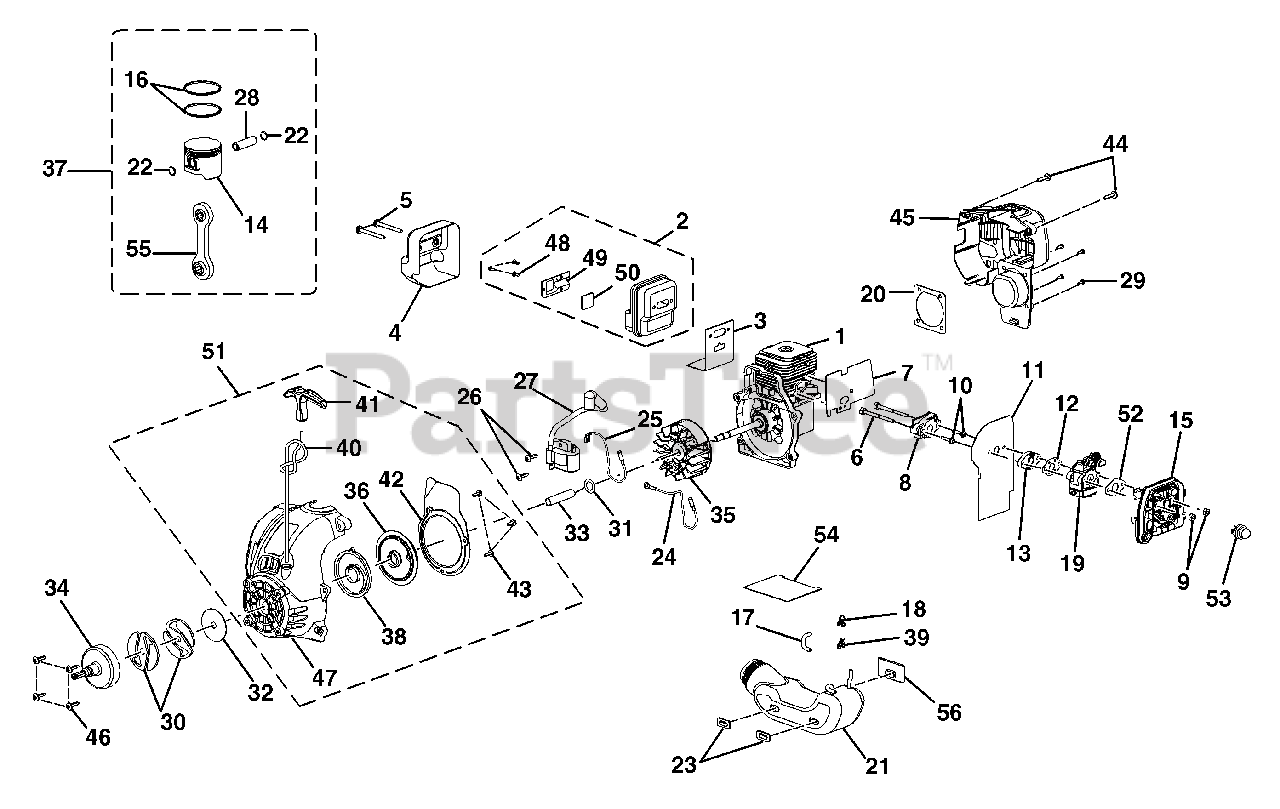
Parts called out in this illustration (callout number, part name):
1	SHORT BLOCK ASSEMBLY
2	MUFFLER ASSEMBLY
3	MUFFLER GASKET
4	HEAT SHIELD
5	SCREW (10-24 X 2-1/8 in. TORX TRUSS HD. SEMS)
6	BOLT (10-27 X 2-3/8 in HEX HD.)
7	HEAT DAM GASKET
9	LOCK NUT (10-24)
10	SCREW (10-24 X 1 in. TORX PAN HD.SEMS)
11	CARBURETOR GASKET
12	CARBURETOR GASKET
14	PISTON W/PIN
15	AIR FILTER BOX
16	PISTON RING 30cc
17	RUBBER TUBING (2 in)
19	CARBURETOR
20	GASKET, C/C COVER
21	FUEL TANK ASSEMBLY
22	RETAINING RING
24	LEAD W/TERMINALS
26	SCREW (8-32 X 1 in. THREAD FORMING)
27	IGNITION MODULE (W/ 3 SEC. KILL)
28	PISTON PIN
29	SCREW (10-24 X 3/4 in. PAN HD TORX)
32	WASHER
34	DRUM & CONNECTOR
35	ROTOR PAWL ASSEMBLY
36	STARTER PULLEY
37	PISTON ASSEMBLY
38	SPRING & CONTAINER
40	STARTER ROPE
41	STARTER GRIP
43	SCREW (8-16 X 1/2 in. THD. FORM)
44	SCREW (10-14 X 7/8 in. THD. FORM)
45	REAR HOUSING
46	SCREW (10-24 X 3/4 in. TRUSS HD.)
47	STARTER HOUSING W/EYELET
48	SCREW (6-20 X 1/4 in. TRI-LOBULAR)
49	OUTLET TUBE
51	COMPLETE STARTER ASSEMBLY
53	PRIMER ASSEMBLY
54	TANK INSULATION GASKET
55	CONNECTING ROD ASSEMBLY
56	RUBBER BUMPER
